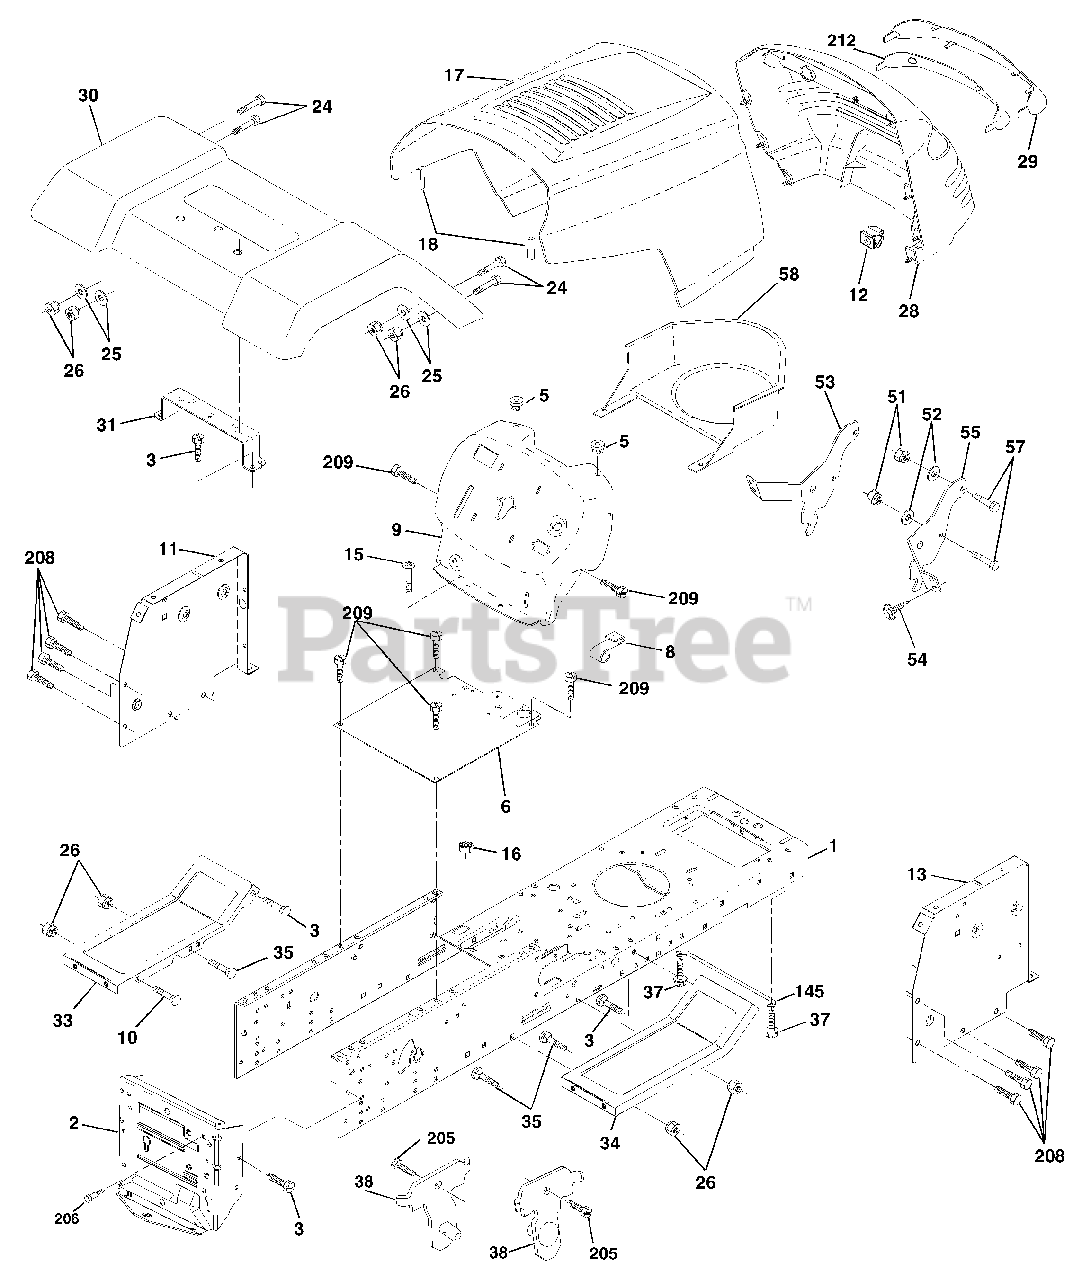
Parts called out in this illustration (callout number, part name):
1	Chassis
2	Drawbar
3	Screw 3/8-16 x 3/4
5	Bumper Hood/Dash
6	Saddle Flat Lt
8	Clip Retainer Slide-On
9	Dash
10	Bolt Rd Hd Sqnk. 3/8-16 Unc x 1
11	Panel Asm. Dash Lh
12	Clip Tinnerman Grile P/L
15	Screw Mach Trhd 5/16-18 Unc x 3/4
16	Nut Keps 5/16-18 Unc
17	Hood
18	Bumper Hood
24	Bolt Fin Hex 3/8-16 Unc x 1 Gr. 5
25	Washer 13/32 x 13/16 x 12 Ga.
26	Nut Lock Hex w/Insert 3/8-16 UNC
28	Grill/Lens Asm
29	Lens Grille Private label
31	Bracket Fender
33	Footrest LH
34	Footrest RH
35	Bolt Rd Hd Sht. Sqnk. 3/8-16 x 3/4
37	Screw Thdrol 5/16-18 x 1/2 Tyt
38	Bracket Asm. Pivot Mower Rear
51	Nut Lock Hex W/Ins. 1/4-20
52	Washer 9/32 x 7/8 x 16 Ga.
53	Bracket Grille LH
54	Screw Hex Wshd 8-18 x 7/8
55	Bracket, Grille RH
57	Bolt Fin Hex 1/4-20 x .75
58	Air Duct Private Label
145	Rod Pivot Chassis/Hood
205	Screw Thdrol 3/8-16 x 1/2
206	Bolt shoulder 5/16-18
208	Screw Thdrol 3/8-16 x 1/2
209	Screw Hex Wsh Thdrol 3/8-16
212	Insert Lens Reflector
